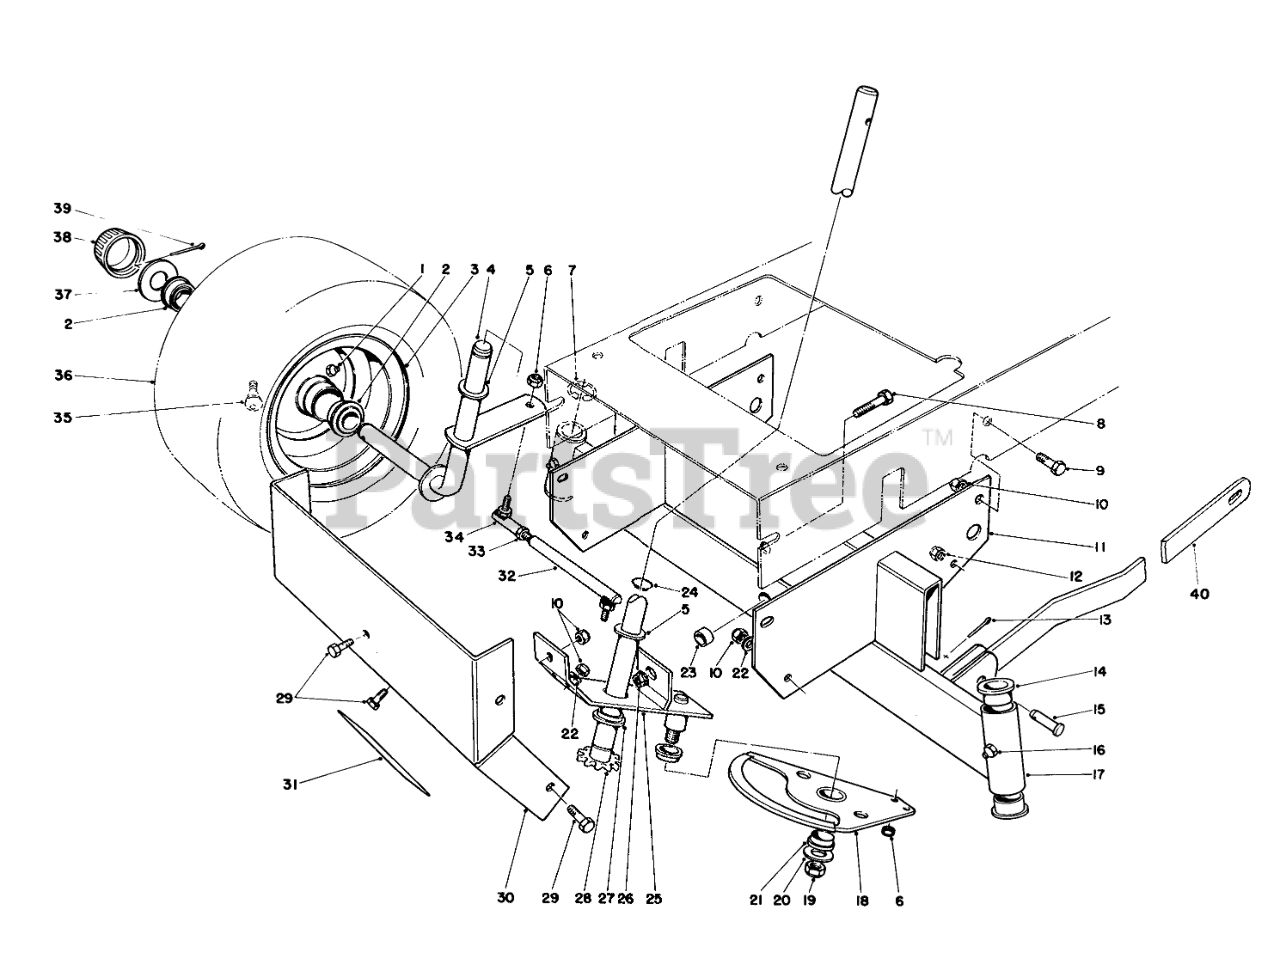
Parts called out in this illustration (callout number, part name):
1	FITTING-GREASE
2	Bearing
4	Spindle RH
5	WASHER-THRUST
6	NUT-LOCK
7	E-RING
8	SCREW-HH
9	SCREW-HH
10	NUT-LOCK, NI
11	Support
12	NUT-LOCK, CONE
13	PIN-COTTER
14	BEARING-FLANGE
15	PIN-CLEVIS
16	GREASE FITTING
17	Axle-Front (Incl. Ref. #14 & 16)
18	Rack-Steering
19	1/2-13 CONELOCK NUT
20	WASHER
21	BEARING-FLANGE
22	WASHER-PLAIN
23	SPACER-AXLE, FRONT
24	RING-RETAINING
25	Rack-Bracket Steering (Incl. Ref. #27)
26	NUT-HF
27	BEARING-FLANGE
28	STEERING SHAFT WA O
29	SCREW-HH
30	Cover-Front
31	Decal-Warning
32	Tie Rod-Steering (Incl. Ref. #32 & 33)
33	NUT-JAM
34	JOINT-BALL
35	STEM-VALVE
36	Tire
37	WASHER-PLAIN
38	Cap-Hub
39	PIN-COTTER
40	Arm-Suspension, Front
